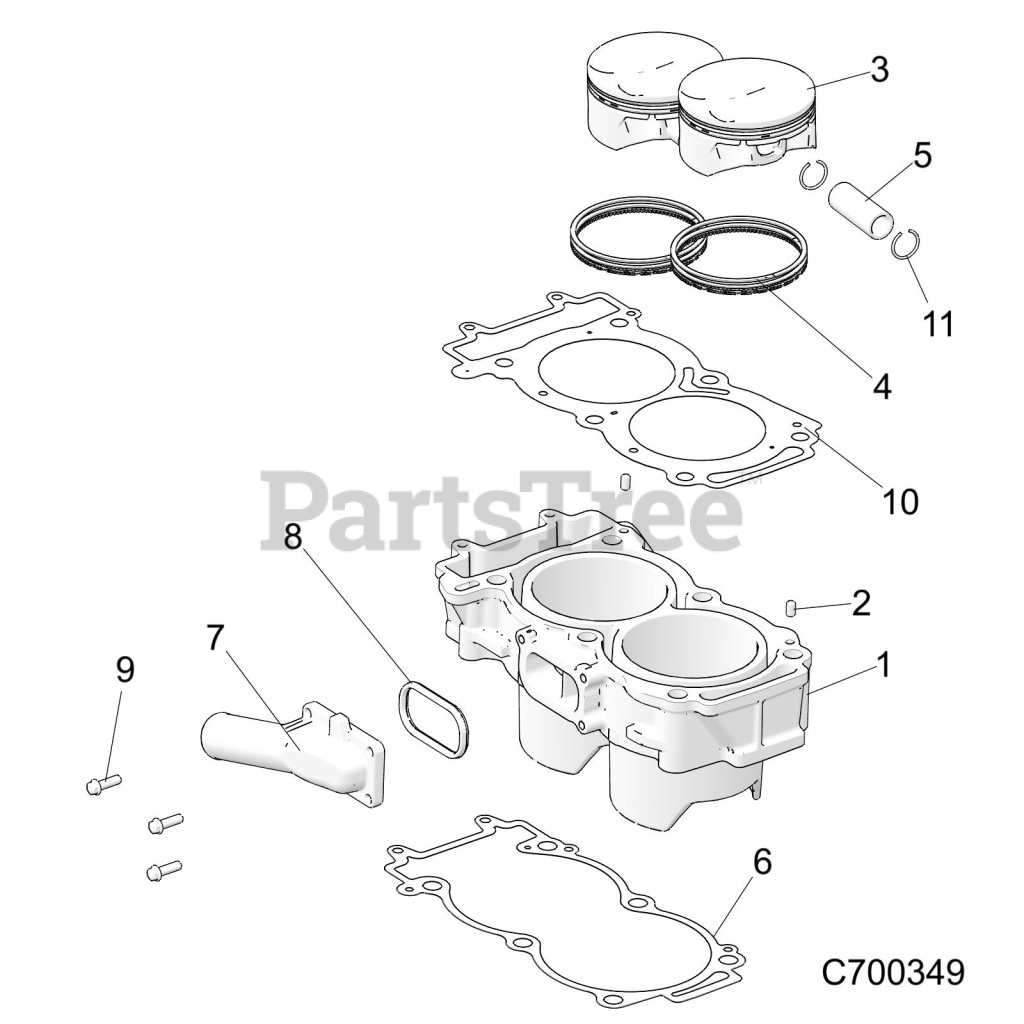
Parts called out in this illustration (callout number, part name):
1	ASM-CYLINDER,875
2	PIN-DOWEL,M6X10
3	ASM-PISTON
4	KIT, PISTON RINGS
5	PIN, PISTON
6	GASKET, BASE, 2 CYL
7	COVER, WATER INLET, CAST
8	GASKET, WATER, INLET
9	SCR-M6X20,HXFLG,0600214
10	GASKET-CYLINDER,HEAD
11	RING-RTG,ROUND,20.0X1.6
